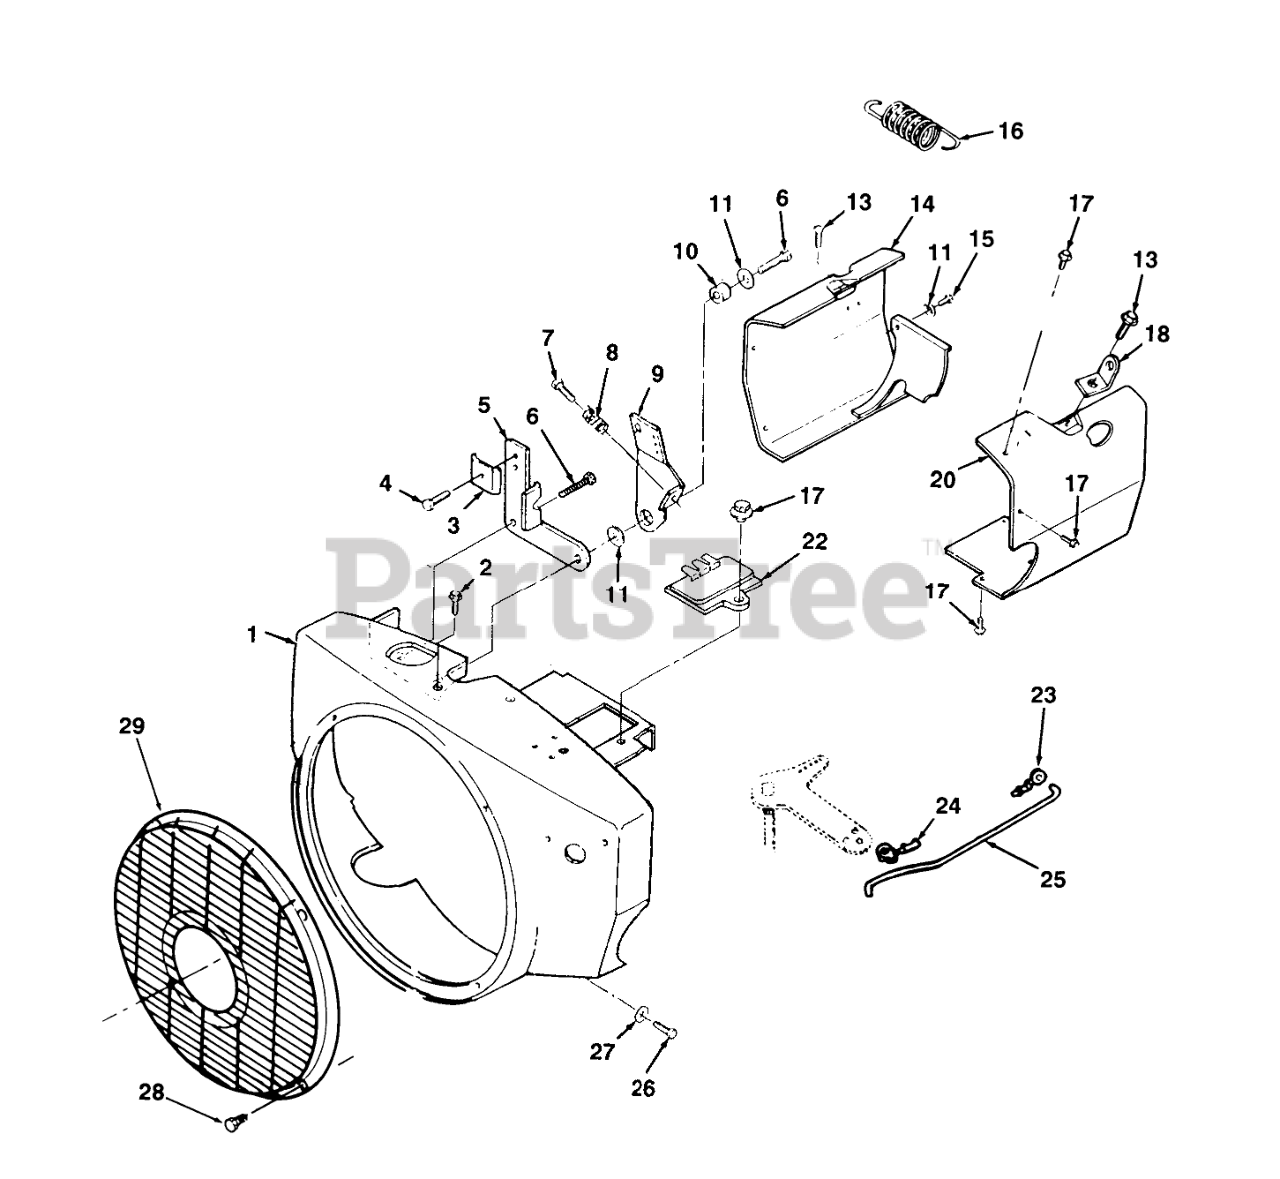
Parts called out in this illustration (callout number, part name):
1	HOUSING-BLOWER
2	SCREW-HWH
4	SCREW-TAPPING
5	Bracket
6	SCREW-HWH
7	SCREW-TAP
8	SPRING
10	BUSHING
11	WASHER-FLAT
13	SCREW-HWH
14	HOUSING-AIR CYLINDER, LH
15	SCREW-HH
16	SPRING
17	SCREW-HWH
18	BRACKET-LIFTING
20	HOUSING-AIR CYLINDER, RH
22	REGULATOR
25	ROD-GOV CONTROL
26	Screw-Tapping
27	WASHER-FLAT
28	SCREW-PAN HEAD
29	GUARD-STATIONARY
